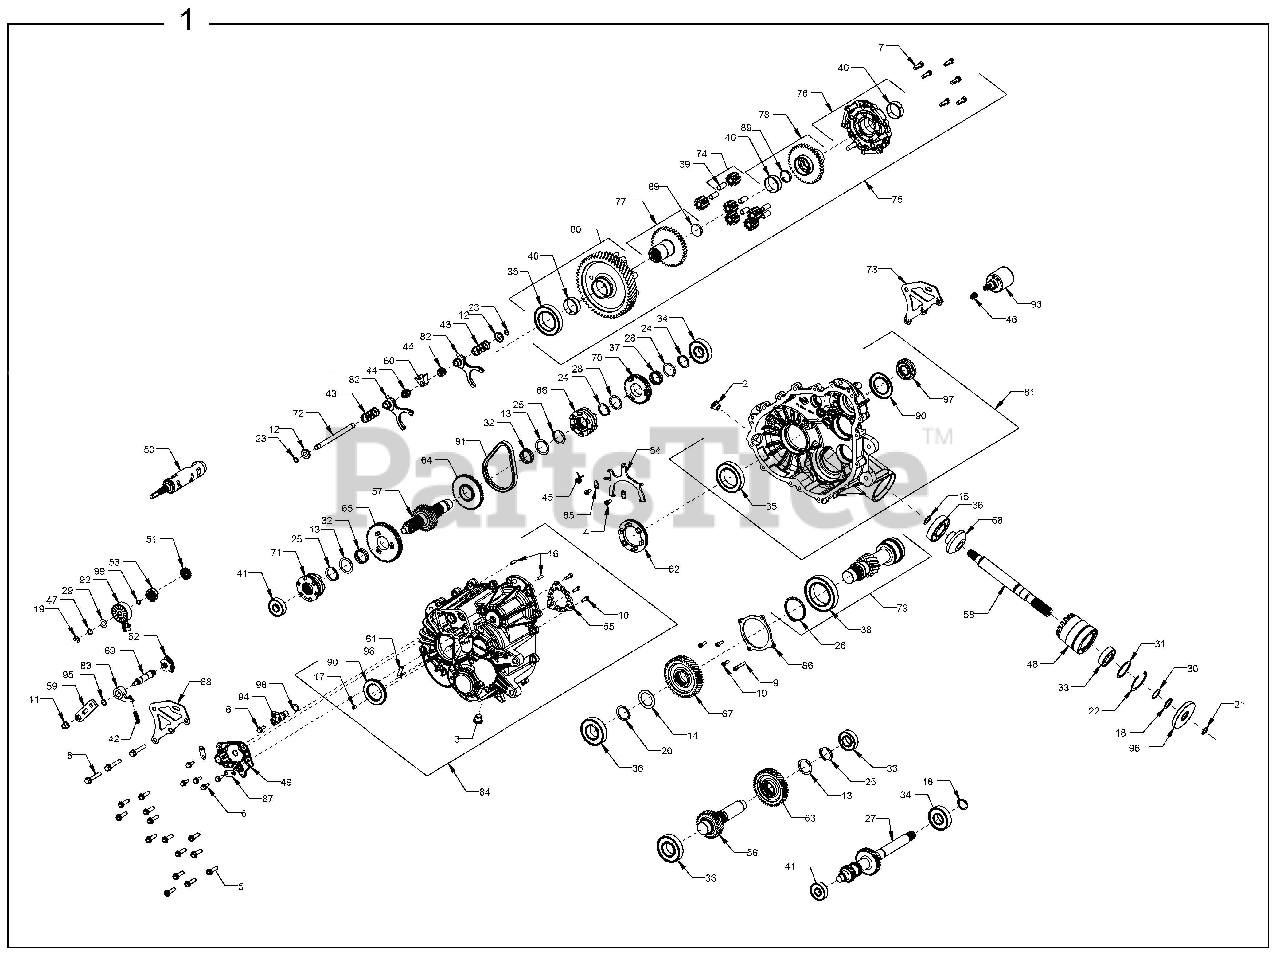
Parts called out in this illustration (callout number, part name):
1	ASM-GEARCASE,DSL
2	PLUG-SKT HD 1SO 6149,M18 X 1.5
3	PLUG-SOCKET HEAD W/MAG,M18X1.5
4	SCREW, TORX PAN HD M6 X 1 X 16
5	SCREW-HEXFLANGEHEAD,M8X1.25X30
7	SCREW-CAP HH,M8 X 1.25 X 20
9	SCR-M6X1.0X40,SOC/CAP(105344)
10	SCR-SCKT HD,CP,M6X1X18(105355)
11	NUT-M8X1.25,HXFLG,NYLN(110093)
12	WASHER-CUP
16	PIN, DOWEL, 6 X 20
17	SPRING-SLOTTED PIN,6MM
18	RING, SNAP
19	RING-RETAINING
20	RING,RETAINING
21	RING,RETAINING,EXTERNAL SHR-66
22	RING,RETAININGBASICINTRNL2.047
23	RING-RETAINING
24	RING,RETAINING
25	RING, RETAINING, EXTERNAL
26	RING, RETAINING
27	SHAFT, INPUT, HELICAL
28	WASHER,THRUST
29	WASHER,THRUST,.446X.88X.025
30	SHIM 1.180 X .995
31	SHIM 2.040 OD X 1.630 ID
32	BEARING,NEEDLE
35	BEARING, BALL
36	BEARING-BALL
37	BEARING,NEEDLE
38	BEARING, BALL
39	BEARING,PLAIN,10X12X25
40	PLAIN,BEARING 40X44X15
41	BEARING, BALL
42	SPRING-COMPRESSION
43	SPRING-COMPRESSION
44	SPRING-COMPRESSION
45	SPRING, TORSION RETURN
46	SPRING,COMPRSSN.54ODX.44IDX.05
47	WASHER-SPRING,210393
48	TUBE, SNORKLE MACH
49	COVER,GEARCASE
50	DRUM-SHIFT,MACH.(255289)
51	GEAR-SECTOR,16T
52	GEAR-SECTOR,31T-CUT TO 11T
53	DETENT STAR
54	SHIFT FORK (270507)
55	PARK PLATE (270509)
56	SHAFT, IDLER, 29T
57	SHAFT, REVERSE, 29T
58	SHAFT-FRONT OUTPUT(285914)
59	BELLCRANK
60	COLLAR-SHIFT
61	TUBE-VENT,90-1/4" HOSE
62	DOG-ENGAGEMENT
63	GEAR, 46T, STAGE 3
64	GEAR-13T,FRONT OUTPUT(352957)
65	SHAFT, SHIFT
66	ENGAGEMENT DOG, 6-FACE
67	GEAR, 46T, STAGE 3
68	GEAR-13T,FRONT OUTPUT(352957)
69	SHAFT, SHIFT
70	GEAR 49T
71	SHIFT DOG, PARK/LOW (353357)
72	RAIL-SHIFT SHAFT(353622)
73	WELD-REAR MOUNT BRKT
74	GEAR SUBASSEMBLY
75	DIFF-LOCKING (411600)
76	SUBASSY-COVER,DIFF (411601)
77	SUBASSY-GEAR,39T SIDE (411607)
78	SUBASSY-GEAR,39T SIDE (411608)
79	ASM-SUB,PINION SHAFT(411759)
80	SUBASSY-GEAR,53T (411797)
81	SUBASSY,LH CASE(411919)
82	SHIFT FORK SUBASSEMBLY
83	ROLLER PAWL
84	SUBASSEMBLY,RH CASE (411982)
85	RETAINER-FORK
86	COVER, BEARING, CENTER DRIVE
87	BRKT-MOUNT(430592)
88	BRKT-REAR MOUNT
89	PLUG,EXPANSION,1 1/4
90	SEAL-TRIPLE LIP,VITON,40X70X7
91	CHAIN, SILENT
92	PIN-GEAR POSITION SWITCH
93	SOLENOID
94	SENSOR-SPEED,TRANS
96	SEAL-TRIPLE LIP 25X80X10
98	O-RING, -113
